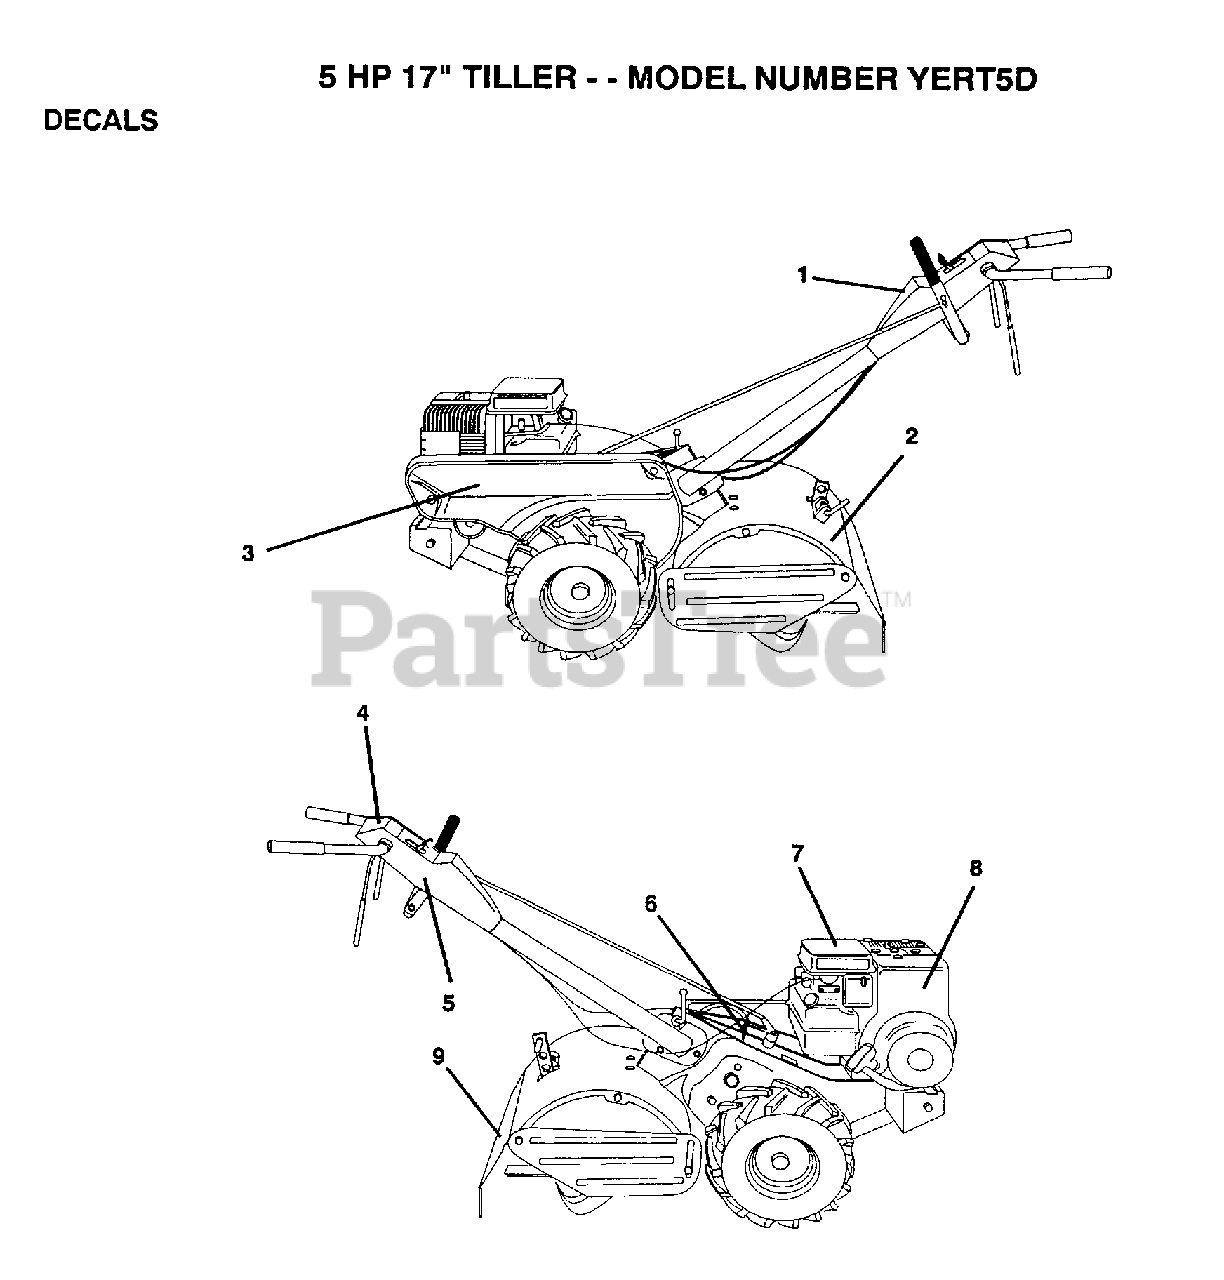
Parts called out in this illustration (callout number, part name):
4	DECAL.INSTRUCTION
5	DECAL TI
7	DECAL TI
